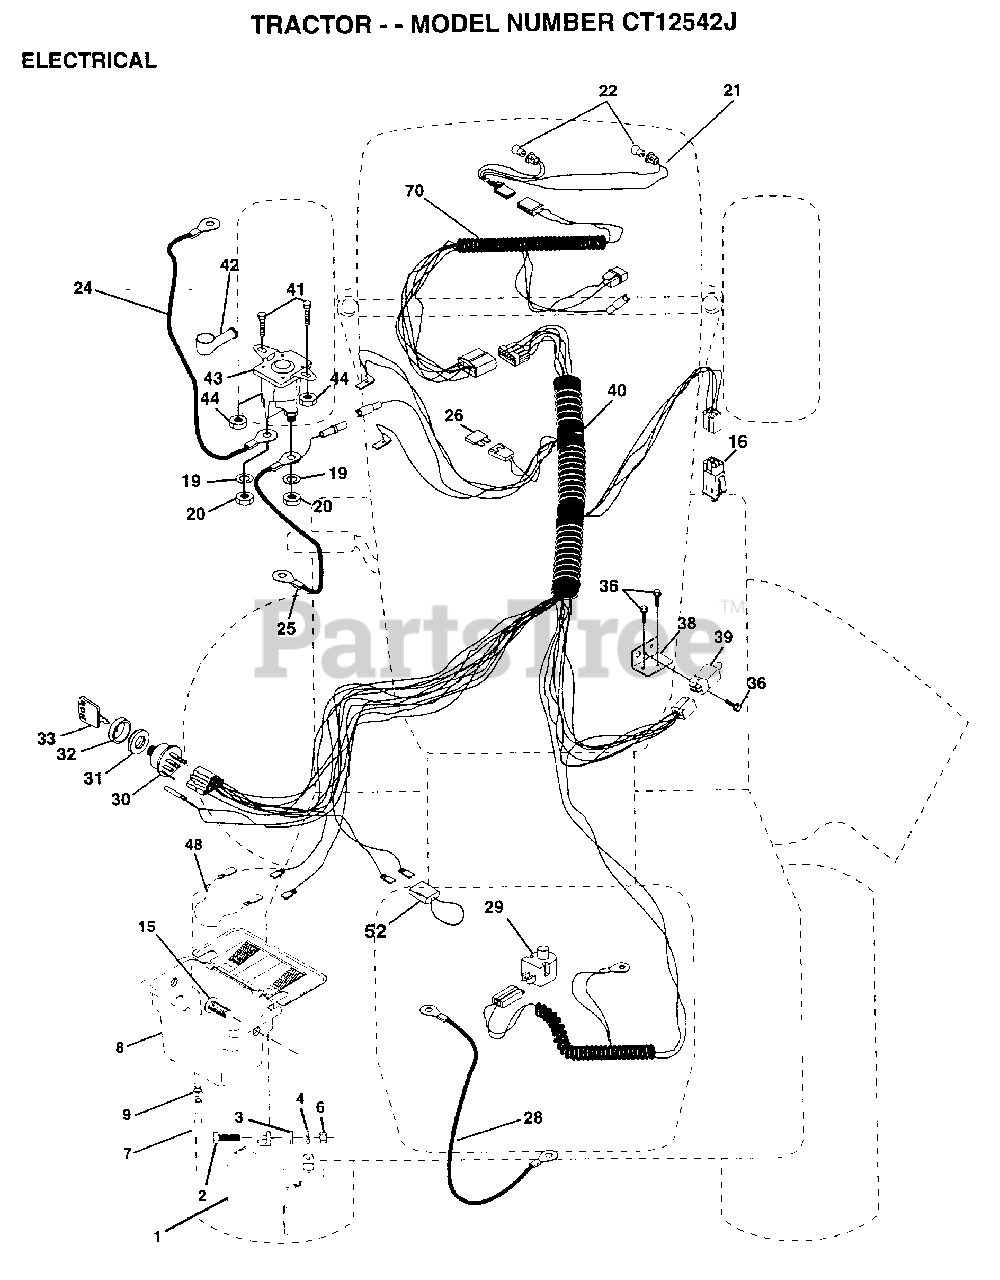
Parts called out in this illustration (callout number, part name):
2	BOLT LT
3	WASHER
4	LOCKWASHER
7	TUBE T
9	HOSE CLAMP T
15	FASTNER.SNAP-IN
16	SWITCH INTERLOCK
20	NUT
21	"HARNESS,LIGHT SOC"
22	HEADLAMP BULB
24	"CABLE T, BATTERY"
25	CABLE.BTRY.6GA.RD
26	FUSE HYT
28	CABLE T
29	SWITCH SEAT
30	SWITCH IGN 4POS
31	NUT IGNITION
32	COVER KEY SWITCH
33	KEY
36	SCREW
38	BRACKET SWITCH IN
39	SWITCH INTERLOCKT
40	HARNESS.IGNITION
41	BOLT HXHD FIN
44	NUT HXKEP 1/4X20
48	ADAPTER AMMETER
52	PROTECTION LOOP
70	HARNESS.ENGINE
